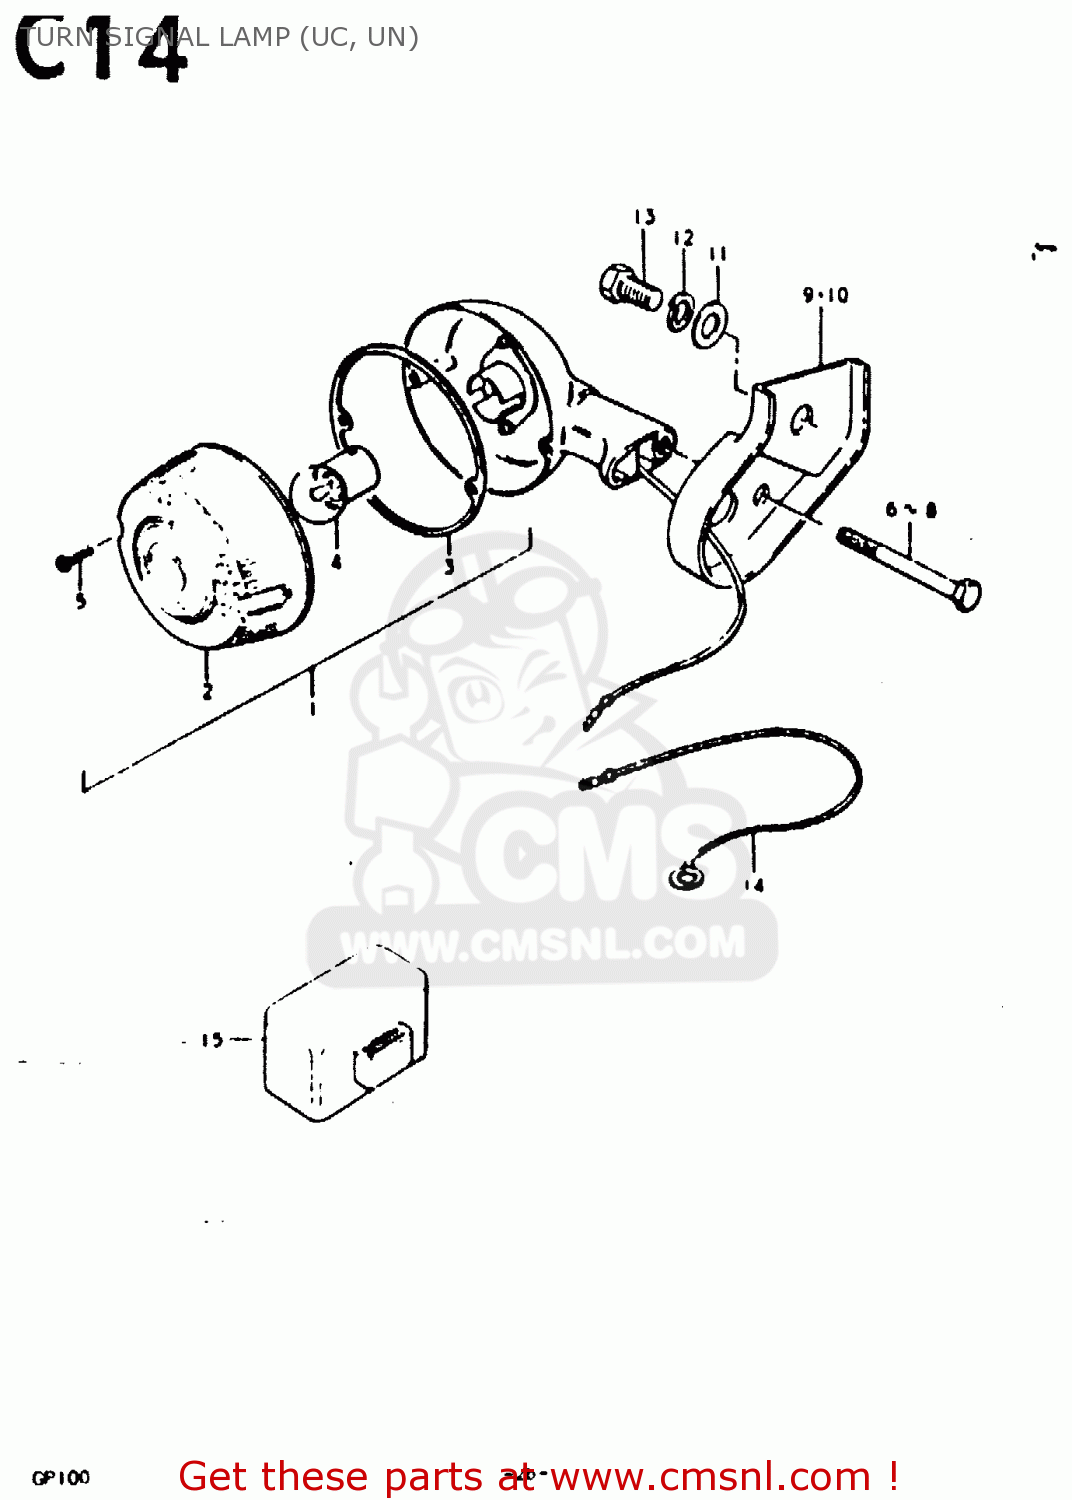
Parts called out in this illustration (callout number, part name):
1	LAMP ASSY, TURN SIGNAL
2	LENS
3	GASKET (NAS)
4	BULB(6V8W,STANLEY,A4115)
5	SCREW
7	BOLT 6X60
8	BOLT 6X60
9	BRACKET, REAR TURN SIGNAL RH
10	BRACKET, REAR TURN SIGNAL LH
11	WASHER
12	LOCK WASHER
13	BOLT
14	LEAD WIRE, FRONT ARTH
15	RELAY, TURN SIGNAL
